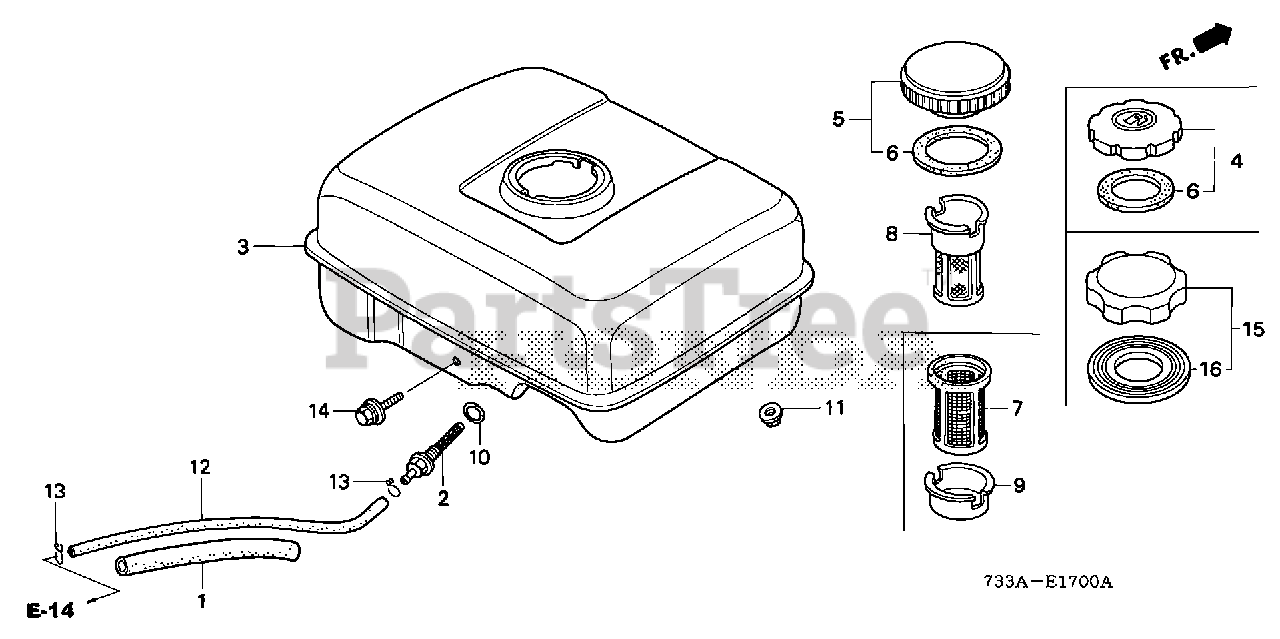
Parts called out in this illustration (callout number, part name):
1	RUBBER, SUPPORTER (107MM)
2	JOINT, FUEL TANK (NOT AVAILABLE)
2	JOINT, FUEL TANK
3	TANK, FUEL *NH31* (MCKINLEY WHITE)
5	CAP, FUEL FILLER (BLACK)
6	GASKET, FUEL FILLER CAP (39X58X3)
7	FILTER, FUEL
9	HOLDER, FUEL FILTER
10	O-RING (14MM) (ARAI)
10	O-RING (14MM) (NOK)
11	NUT, FLANGE (6MM)
12	BULK HOSE, FUEL (4.5X3000) (4.5X140)
13	CLIP, TUBE (B8)
14	BOLT, FLANGE (6X25)
